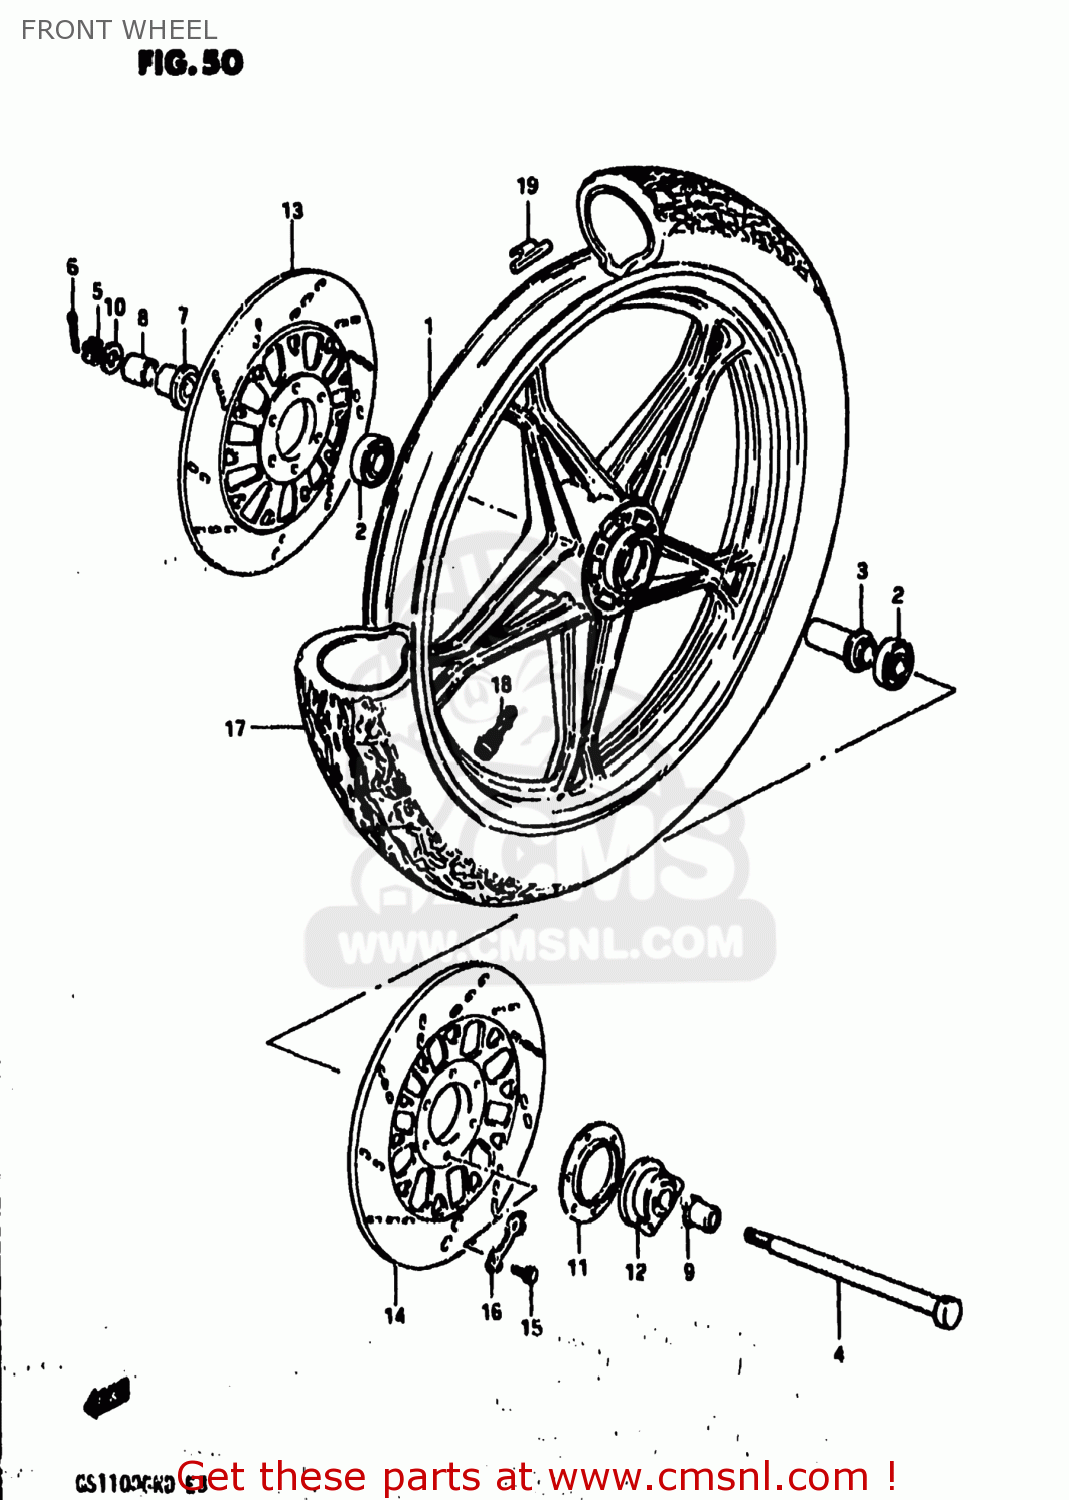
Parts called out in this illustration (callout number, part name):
1	CASTING WHEEL,FRONT 2.15
2	BEARING
3	SPACER,FR HUB BEARING
4	AXLE,FRONT
5	NUT 12MM
6	COTTER PIN
7	SPACER,FR AXLE,R
8	SPACER
9	SPACER,FRONT AXLE
10	WASHER
11	DUST SEAL,SPEEDOMETER GEAR BOX
12	BOX ASSEMBLY,SPEEDOMETER GEAR
13	DISC,FR BRAKE,R
14	DISC,FR BRAKE,L
15	BOLT(8X25)
16	WASHER
17	TIRE,FRONT
18	VALVE ASSEMBLY,WHEEL RIM,J
19	BALANCER,WHEEL
